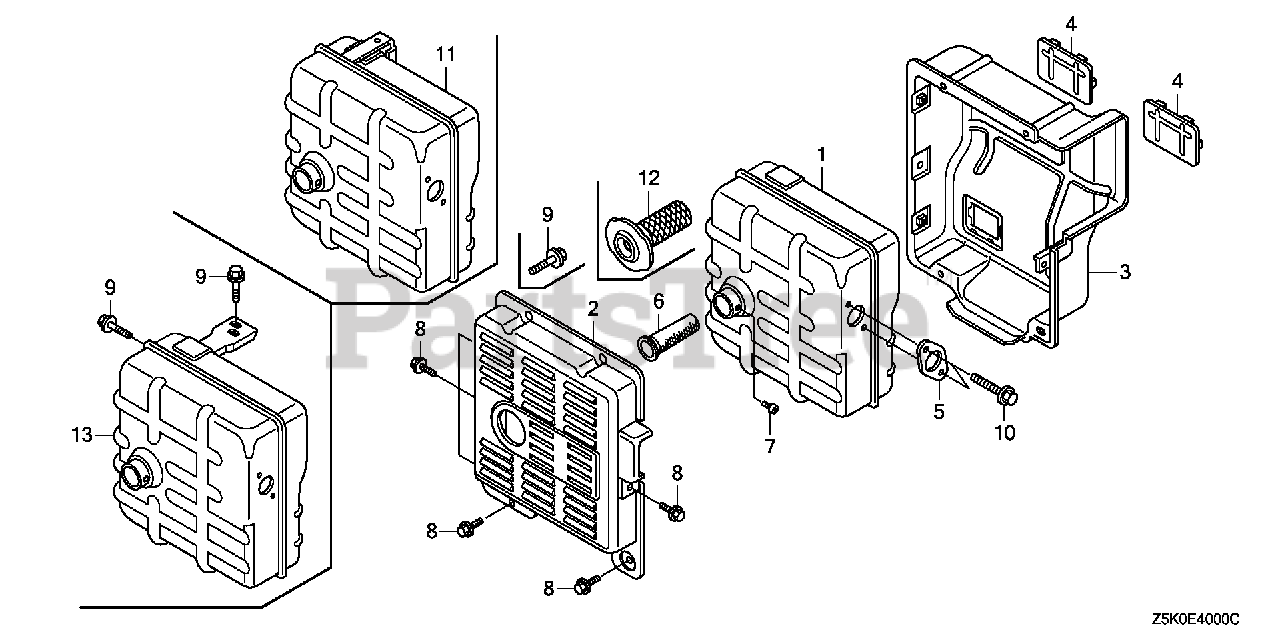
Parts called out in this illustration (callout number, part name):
5	GASKET, EX. PIPE
6	ARRESTER, SPARK
7	SCREW, TAPPING (4X8)
7	SCREW, TAPPING (4X6)
9	BOLT, FLANGE (8X16)
10	BOLT, FLANGE (8X20)
11	MUFFLER (SDMO)
12	ARRESTER, SPARK
